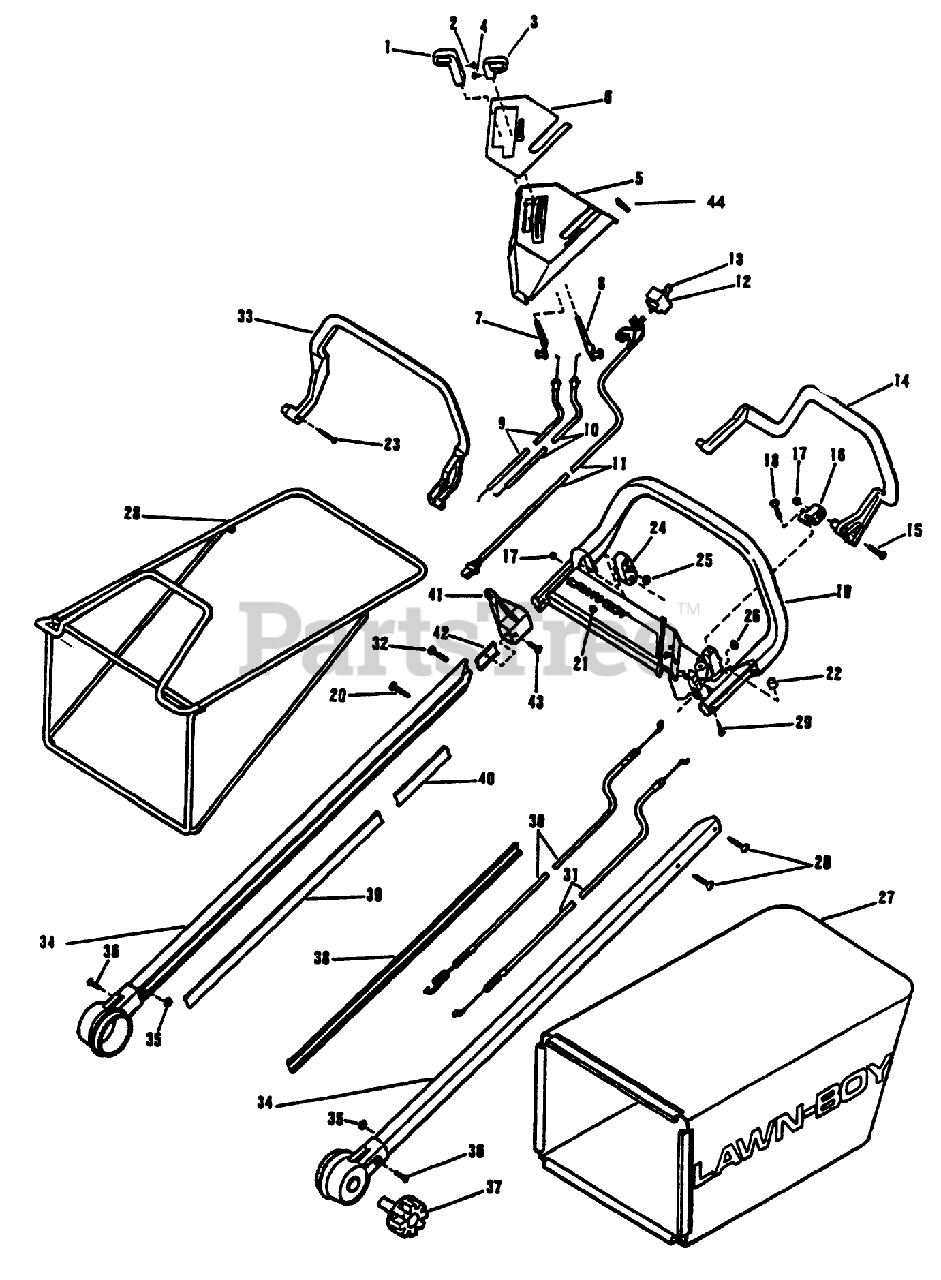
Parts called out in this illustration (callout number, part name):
1	KNOB & SCREW AY
5	UPPER CVR&DECAL AY
9	CABLE AY. WESCON
10	CABLE
14	BAIL-S.P. *
16	PIVOT BAIL PL
17	LOCKNUT FLAN
20	SCREW
24	BLOCK BAIL PL
25	LOCKNUT E
30	CABLE AY
31	CABLE ASSEMBLY
32	SCREW-TRUSS
34	HANDLE SHAFT AY
35	LOCKNUT FLAN
37	KNOB-HDLE MT.ASM*B
38	INSERT - HANDLE
42	NUT LB
